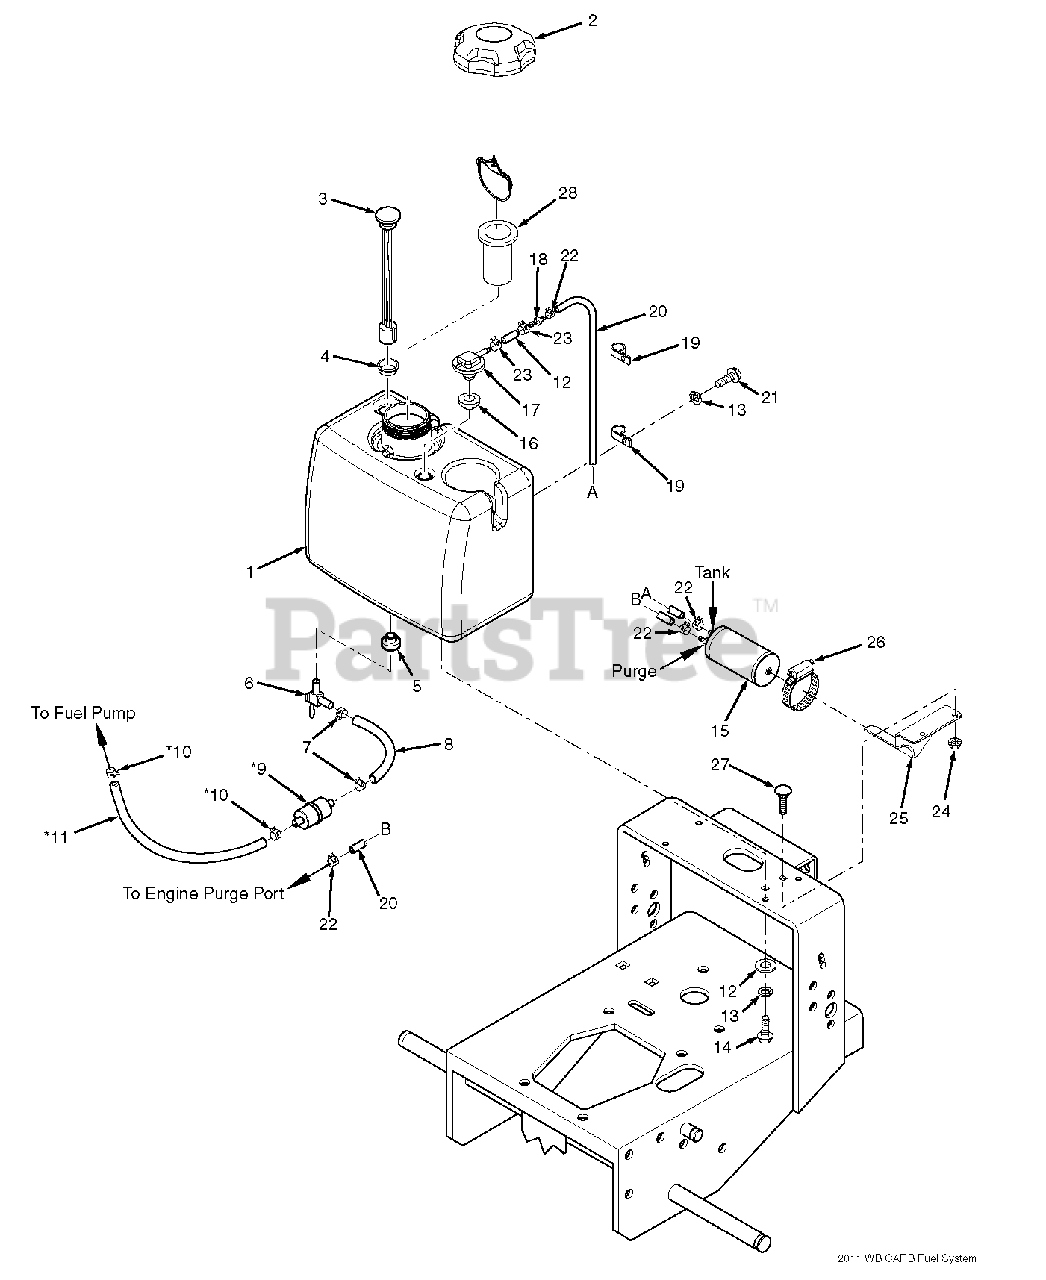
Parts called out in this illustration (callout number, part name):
1	Fuel Tank Assembly
2	Fuel Cap w/ Teether (C.A.R.B.)
3	Fuel Gauge Assembly
4	Seal, Fuel Gauge
5	Bushing, .56 Dia. Viton
6	Ball Valve w/Screen
7	Clamp, Fuel Hose
8	Fuel Hose, 1/4" ID
9	Fuel Filter
10	Clamp, Fuel Hose
11	Fuel Hose
12	Hose, Vapor Recovery 1/4"
13	Lockwasher, 5/16" Spring
14	Bolt, Hex Head 5/16-18 x 1"
15	Carbon Canister
16	Grommet, Viton,
17	Fitting, Remote Vent
18	Mender, 1/4 x 3/16 w/.02 Hole
19	Clamp, 3/8"
20	Hose, Vapor Recovery 3/16"
21	Bolt, Hex Head 5/16-18 x 3/4"
22	Clamp, Vapor Recovery Hose 3/16"
23	Clamp, Fuel Hose 7/32" ID
24	Nut, Serrated Flange 5/16-18
25	Bracket, Canister Mounting
27	Bolt, Carriage 5/16-18 X 1"
28	Tube, Fuel Tank Insert - 4"
